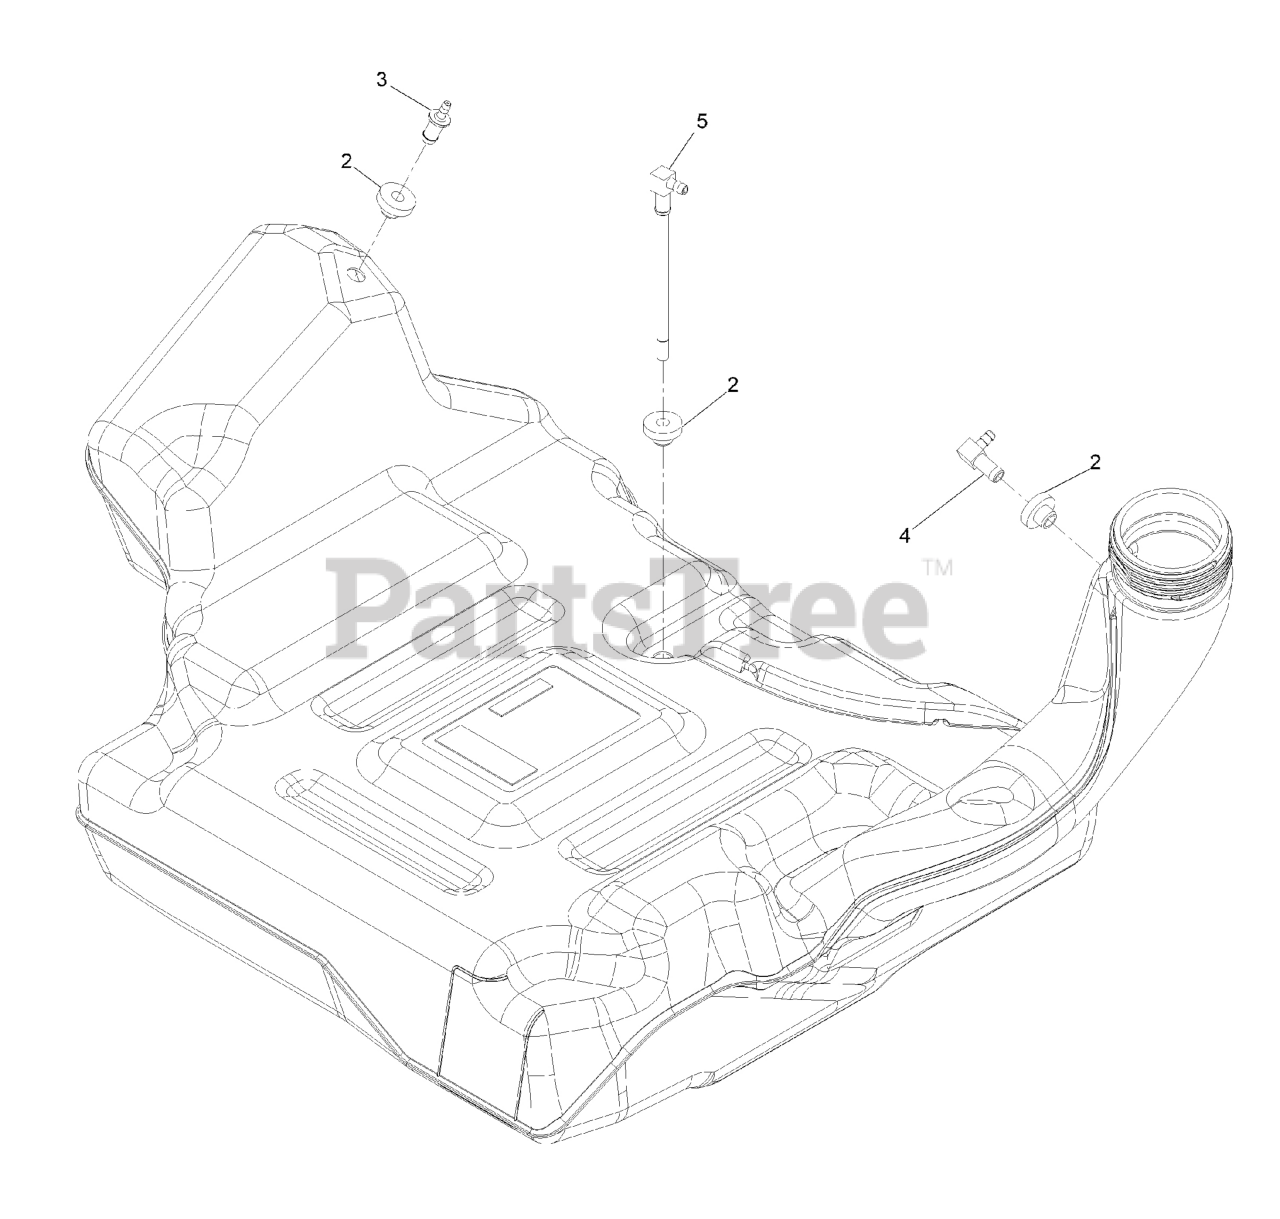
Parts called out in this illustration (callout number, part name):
2	BUSHING
3	FITTING-ORIFICE, STRAIGHT
4	FITTING-90 DEG
5	FITTING,FUEL W/LINE AND SCREEN
